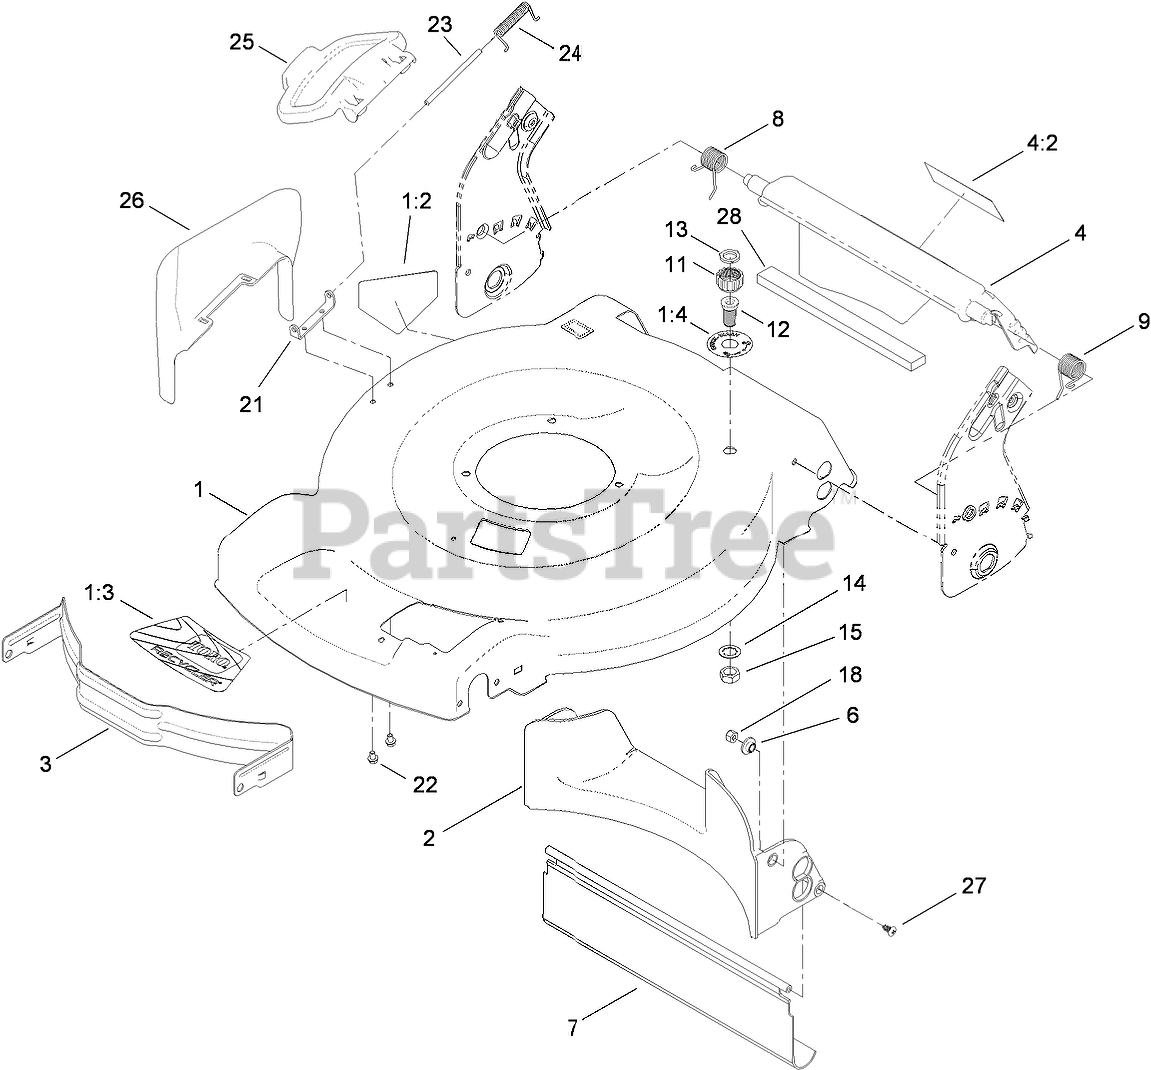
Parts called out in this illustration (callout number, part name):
1	HOUSING ASM
1:2	DECAL-DANGER
1:3	DECAL-RECYCLER
1:4	DECAL-PORT, WASHOUT
2	BAFFLE-REAR
3	BAFFLE-FRONT
4	REAR DEFLECTOR ASM
4:2	DECAL-WARNING
6	WASHER-STEPPED, BAFFLE
7	SHIELD-TRAILING
8	SPRING-TORSION
9	SPRING-TORSION
11	COUPLING-HOSE, WASHOUT PORT
12	PORT-WASHOUT
13	WASHER-SEAL, WASHOUT PORT
14	WASHER-TOOTH, INTERNAL
15	NUT-JAM
18	NUT-LOCK, NI
21	BRACKET-COVER
22	SCREW-HWH
23	ROD-COVER
24	SPRING-TORSION
25	DEFLECTOR-SIDE
26	CHUTE-DISCHARGE, SIDE
27	SCREW-PTH
28	FOAM-SEAL
